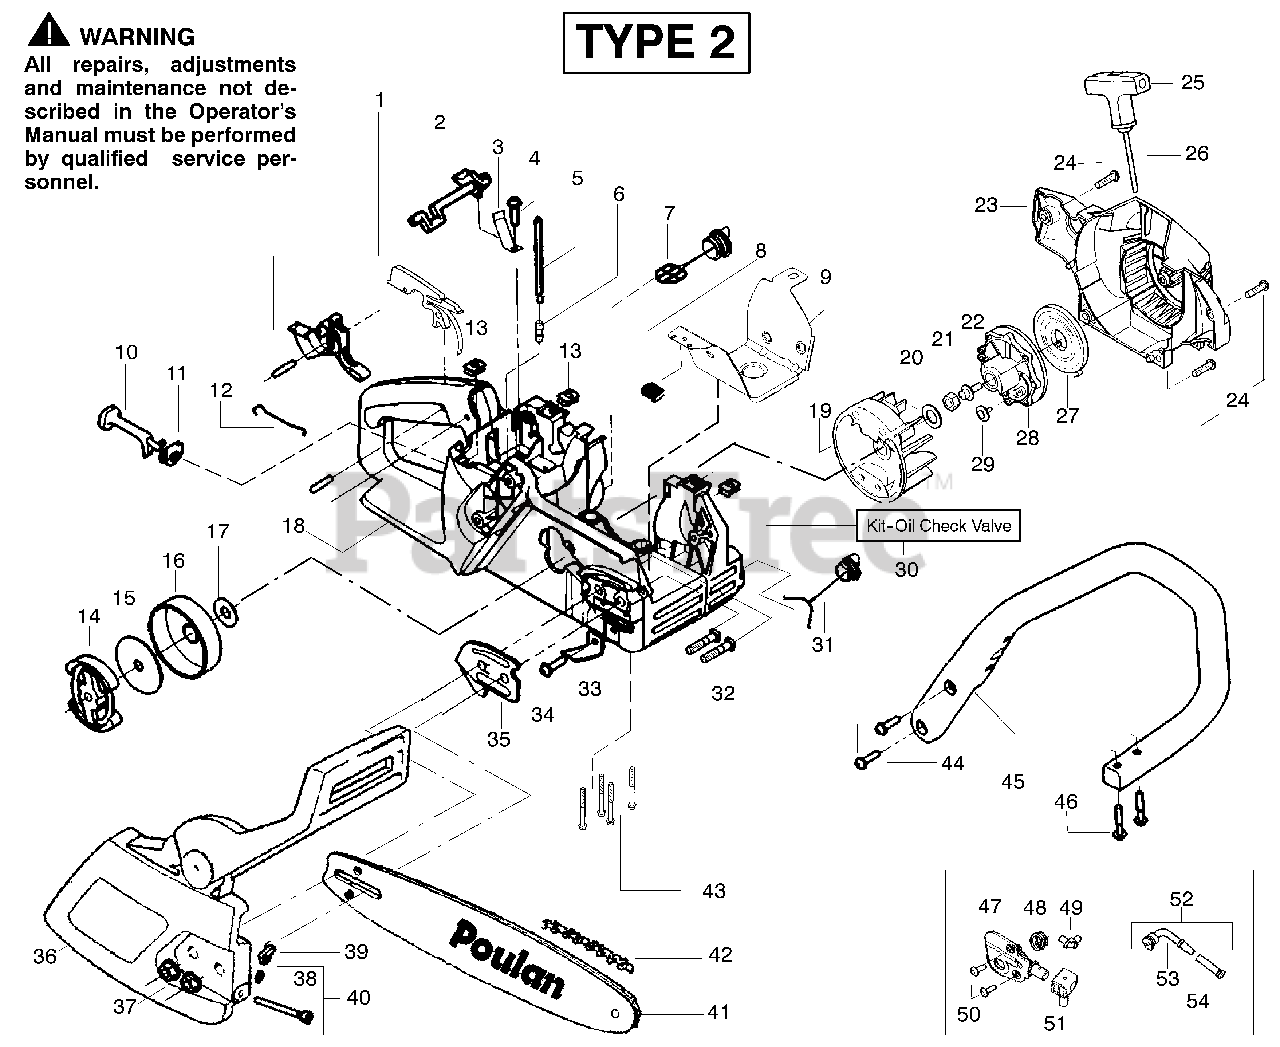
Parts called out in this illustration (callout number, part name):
1	Kit-Trigger & Lockout
2	Lever-Switch
3	Spring-Switch
5	Kit-Fuel Line
6	Fitting - Fuel Line
7	Assy-Fuel Cap w/ret.
8	Clip - "U"
9	Shield - Heat
10	Lever-Choke
11	Grommet-Choke Lever
12	Wire-Throttle
13	Nut-Speed
14	Assy.-Clutch
15	Washer-Clutch
16	Assy-Drum W/brg.
17	Washer - Thrust
18	Kit-Chassis Assy.
19	Assy-Flywheel
20	Washer-Flywheel
21	Nut-Flywheel
23	Housing-Fan
25	Handle-Starter
26	Kit-Rope
27	Spring-Starter
28	Pulley-Starter
30	Kit-Oil Check Valve
31	Assy-Oil Cap
32	Bolt - Bar
33	Chain Catcher
35	Plate-Bar Mounting
36	Assy.-Chain Brake
37	Nut-Bar Mounting
38	Retainer-Bar Adjust
39	Pin-Bar Adjust
40	Kit-Bar Adjust
41	Bar- 16"
42	Chain- 16"
45	Handle-Front
47	Kit-Oil Pump
48	Gear-Worm Spring
49	Elbow-Oil Pickup
51	Block-Seal
52	Assy-Oil-Pickup
53	Pickup-Oiler
54	Filter-Oil
